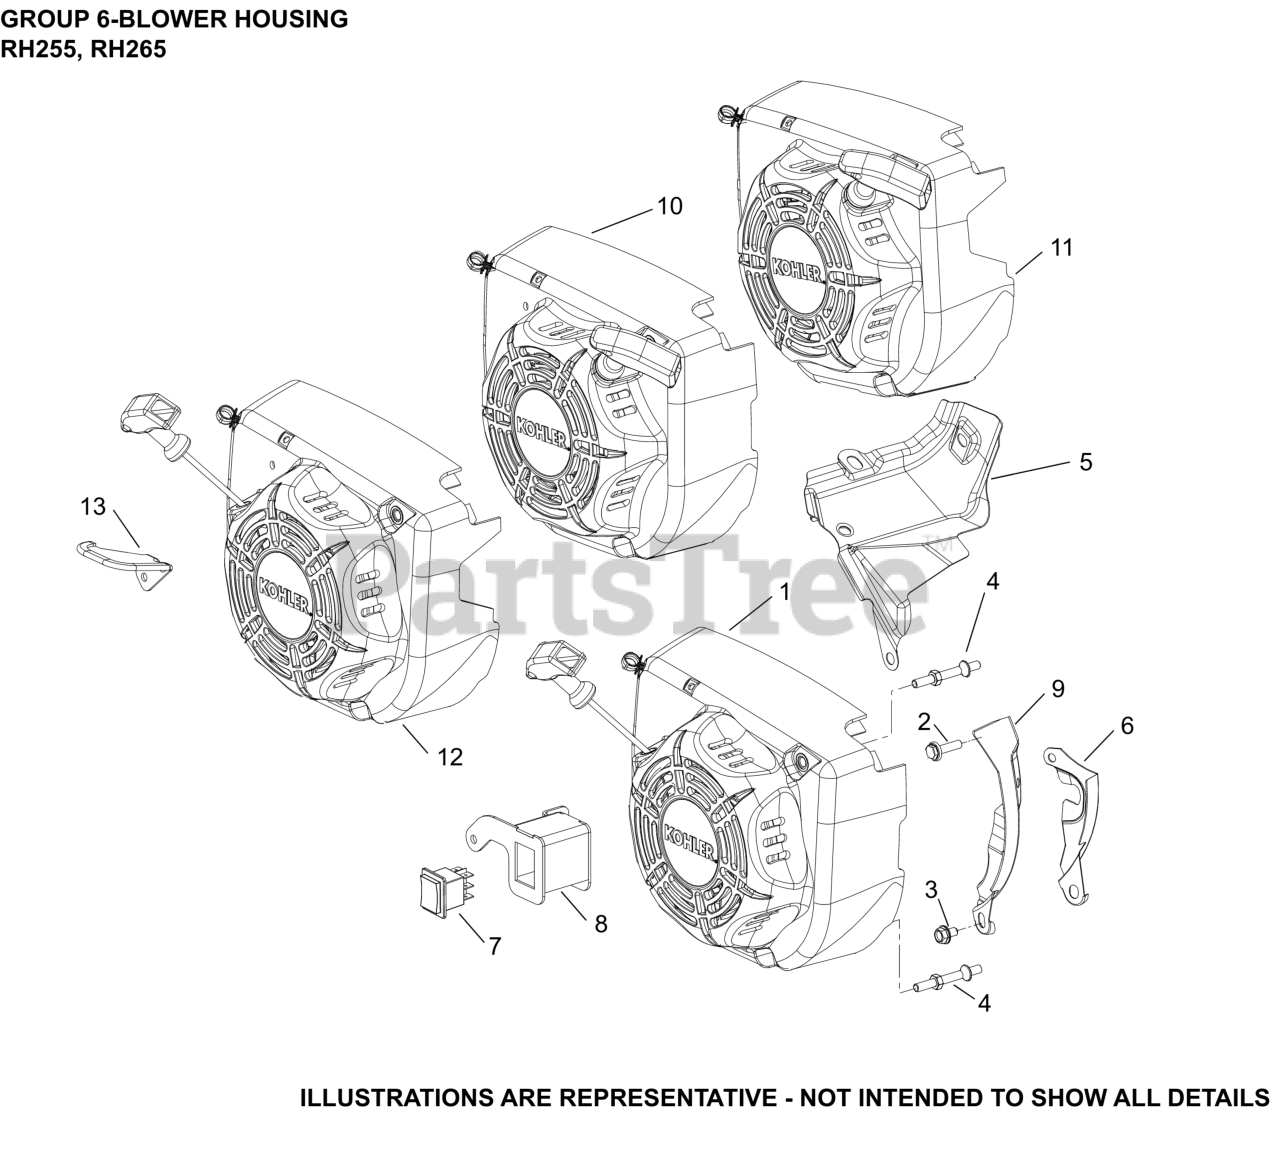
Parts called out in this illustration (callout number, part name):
3	SCREW, HEX FLANGE (M6)
4	STUD, BLOWER HOUSING MOUNTING
5	SHIELD ASSEMBLY, CYLINDER HEAD
9	SHIELD, FLYWHEEL
10	HOUSING, BLOWER RECOIL ASSEMBLY
13	GUARD, ROPE
